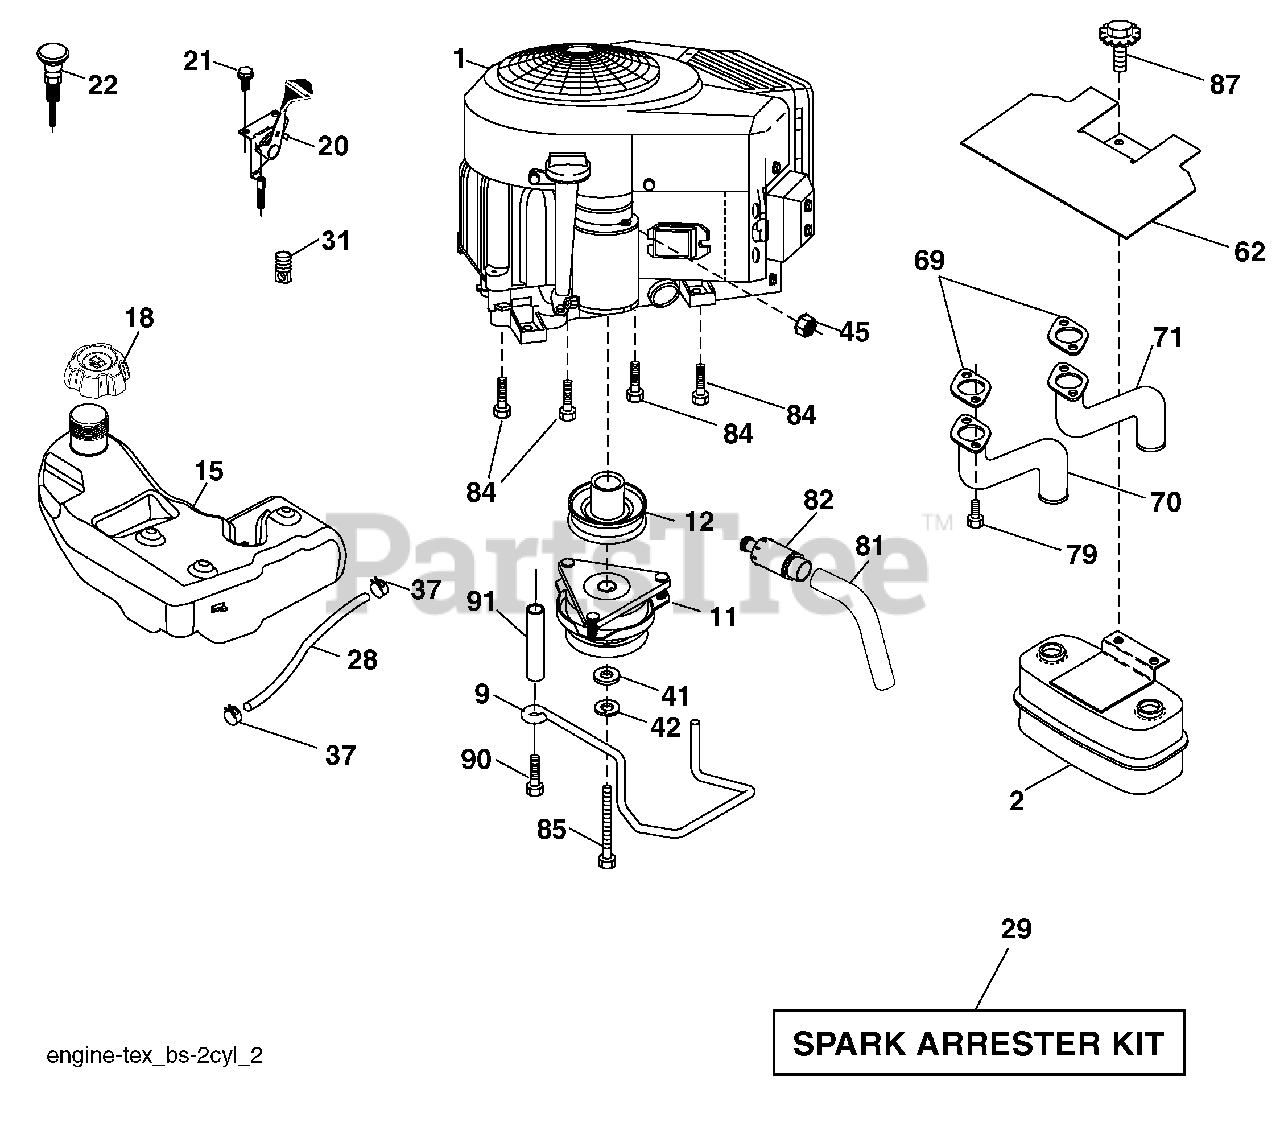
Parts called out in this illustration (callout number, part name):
2	Muffler
9	Keeper Belt Engine
11	Clutch Electric
12	Pulley Engine
15	Tank Fuel
18	Cap Asm.
20	Control Throttle
21	Screw #10 x 0.750 BOS Thread
22	Control Choke
28	Fuel Line
29	Spark Arrester Kit
31	Clip Push-In Hinged
37	Clamp Hose
41	Washer 1-1/2 OD x 15/32 ID x .250
42	Washer Lock 7/16
45	Nut Keps Hex 1/4-20 unc
62	Shield Heat Muffler
69	Gasket
70	Exhaust Tube LH
71	Exhaust Tube RH
79	Screw Socket Head 5/16-18 x 1
81	Tube Drain Oil Easy
82	Plug Drain Oil
84	Screw 3/8-16 x 1-1/4
85	Bolt Hex 7/16-20 x 3.75 Gr. 5
87	Bolt 5/16-18 x 1
90	Screw 3/8-16 x 1
91	Bushing 1.375 OD
